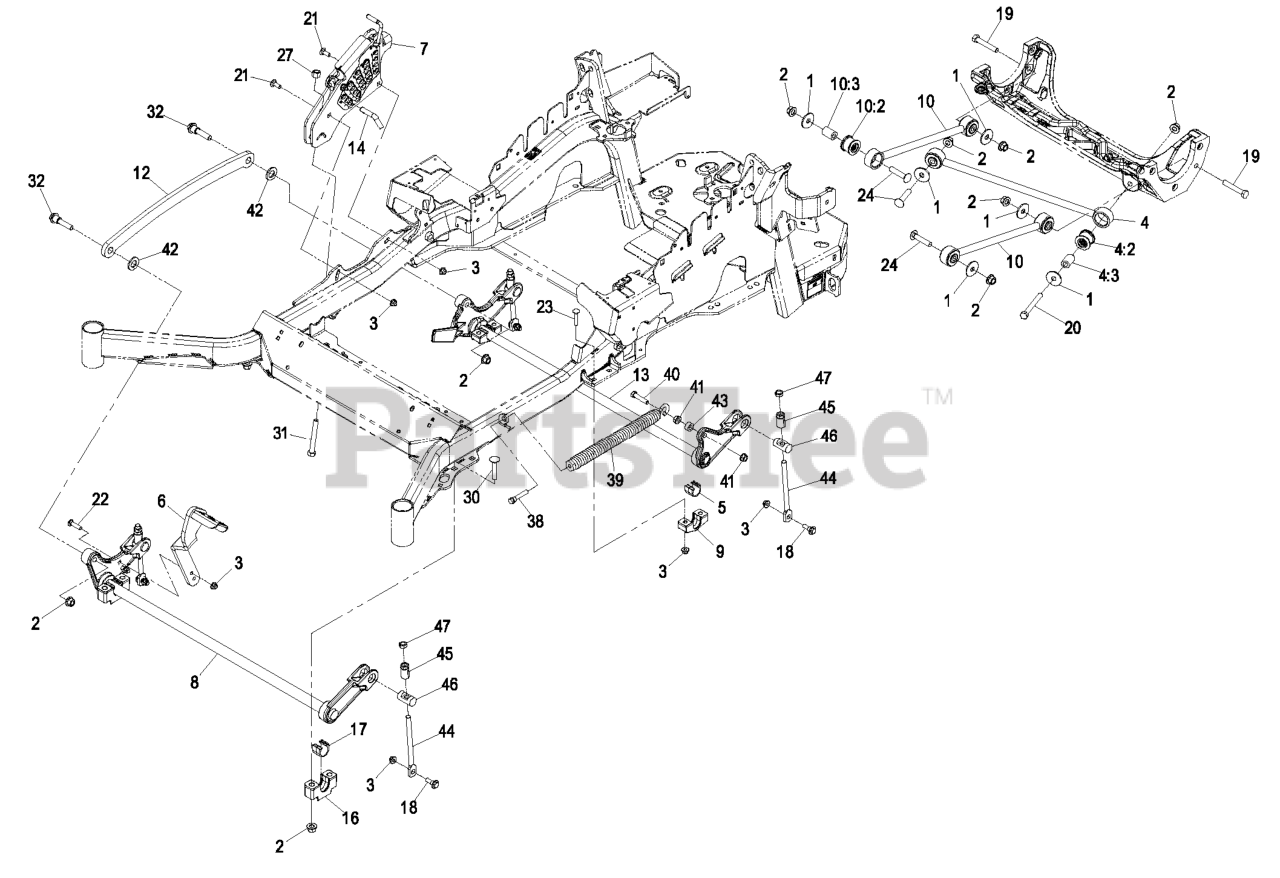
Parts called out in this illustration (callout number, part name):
1	WASHER-THRUST
2	Nut-Lock 1/2-13
3	NUT-HF, NI
4	PANHARD ROD ASM
4:2	BUSHING-SUSPENSION, RUBBER
5	BEARING-CROSS SHAFT, REAR
6	LEVER-FOOT
7	HOC ASM
10	DECK STRUT ASM
10:2	BUSHING-SUSPENSION, RUBBER
12	LINK-LIFT, DECK
13	LIFT-DECK, REAR
14	PIN-HOC
16	SUPPORT-CROSS SHAFT, BEARING
17	BEARING-CROSS SHAFT, FRON
18	SCREW-SHOULDER, HHF
19	SCREW-HH
20	SCREW-HH
21	BOLT-CARR
22	SCREW-CARR
23	SCREW-CARR
24	SCREW-CARR
27	NUT-LOCK, NI
30	Bolt-Carriage 1/2-13 X 2 1/2 Spl Neck
31	BOLT-TAP
32	SCREW-HHF, SHOULDER
38	BOLT-SHOULDER
39	SPRING-EXTENSION
40	SCREW-HH
42	WASHER-FLAT
44	LINK-ADJUSTER, DECK LIFT
45	ADJUSTER-LIFT, DECK
46	TRUNNION
47	NUT-JAM
